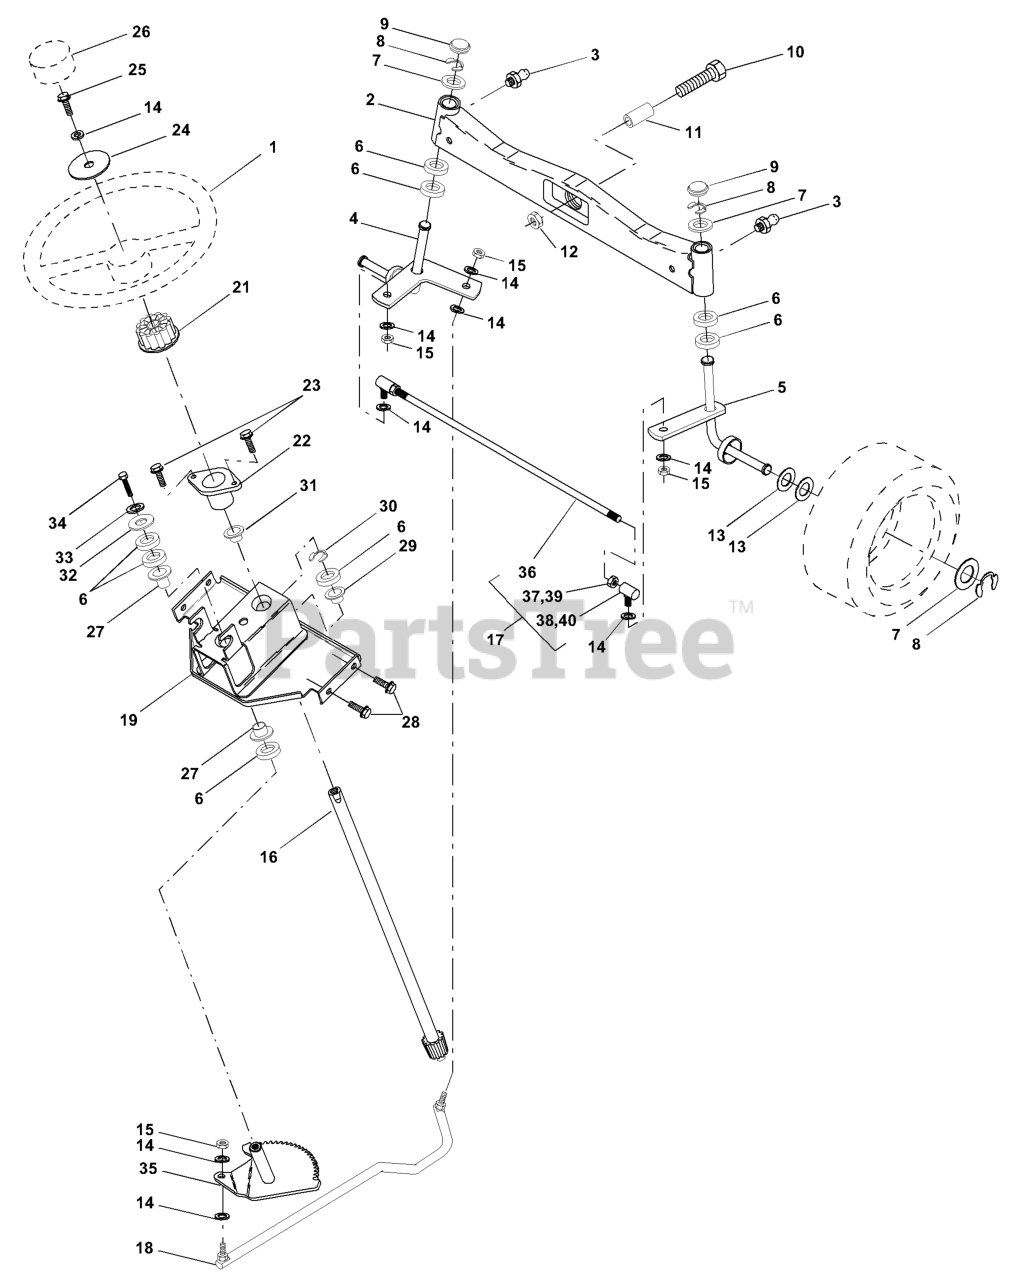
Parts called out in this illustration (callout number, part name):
1	STEERING WHEEL
2	FRONT AXLE ASSY
3	ZERK M
4	SPINDLE ASSY LH
5	SPINDLE ASSY RH
6	BEARING RACE
9	CAP.SPINDLE.BLACK
10	Bolt, Fin Hex 5/8-11 x 2-3/4
11	TUBE, PIVOT AXLE
12	NUT-LOC,FLANGE LT
14	WASHER, LOCK 3/8
15	NUT
16	SHAFT STEERING GT
17	ROD ASSY/TIE BALL
18	DRAGLINK-BALL JOINT SOLID
19	SUPPORT ASSEMBLY
21	ADAPTER LT
22	BUSHING LT
23	SCREW LT
24	WASHER T
25	BOLT
26	INSERT,STR WHEEL
27	BRNG T
28	SCREW
29	BEARING-FLANGE GT
30	Ring, Klip Truarc #5304-75
31	BUSHING.NYLINER.
33	WASHER.LOCK.HVY.HLCL.SPR.5/16
34	BOLT
35	GEAR.ASM.SECTOR.
36	TIE ROD
38	JOINT
39	NUT
